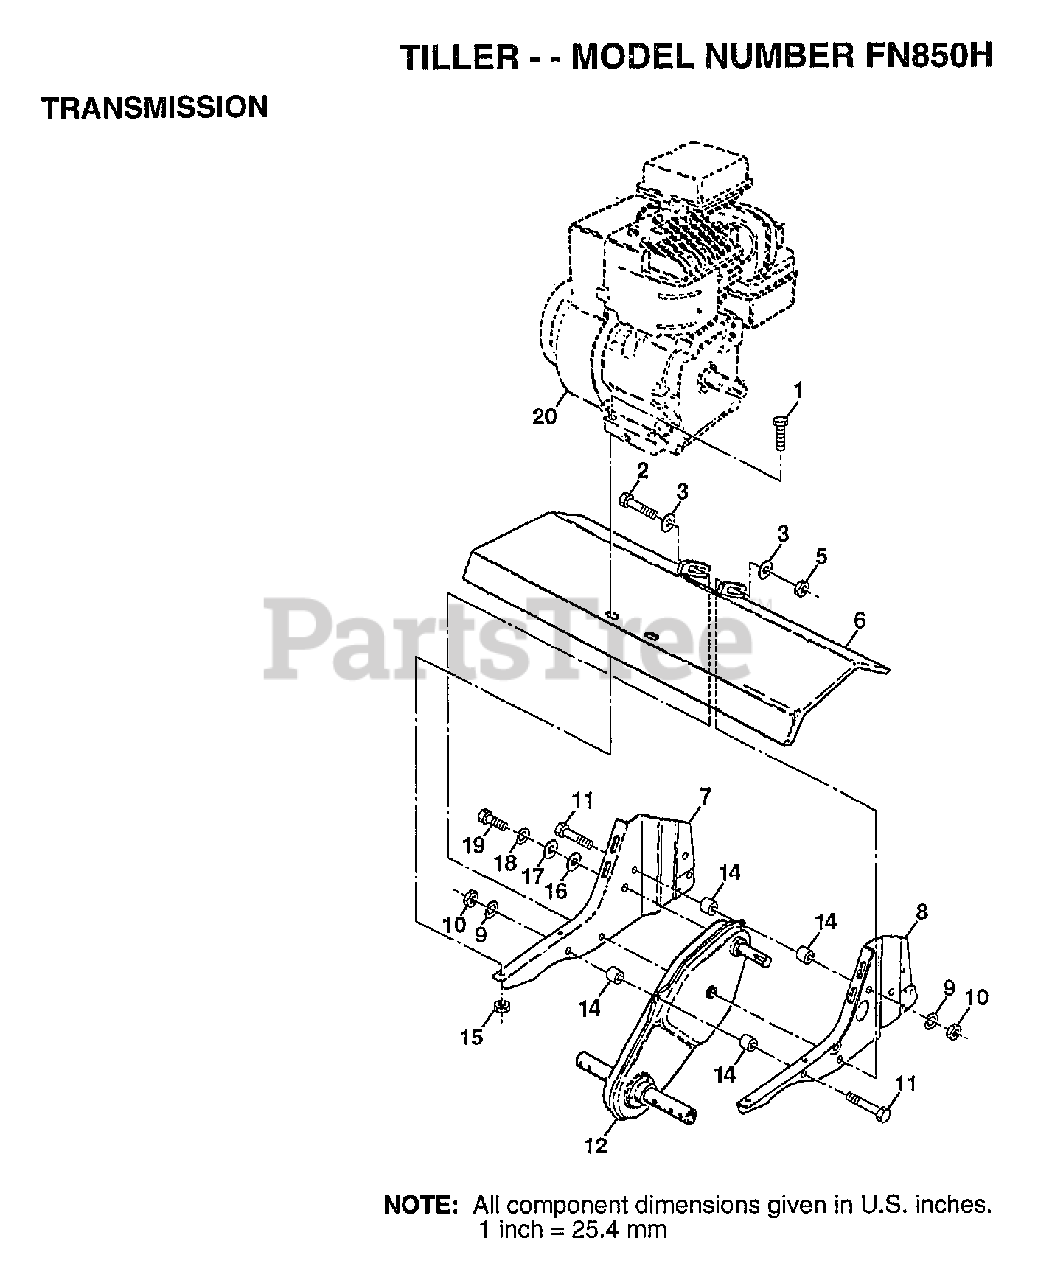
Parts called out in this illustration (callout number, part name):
1	BOLT.HEX.5/16-1.5
2	BOLT HEX 3/8-16
3	WASHER
5	NUT
6	"SHIELD, TINE"
7	BRACKET.ENGINE.RH
8	BRKT.ENGINE.LH
9	LOCKWASHER
10	NUT.HEX.5/16-18
14	SPLIT SPACER RT
16	WASHER
17	WASHER
18	LOCKWASHER
19	BOLT
